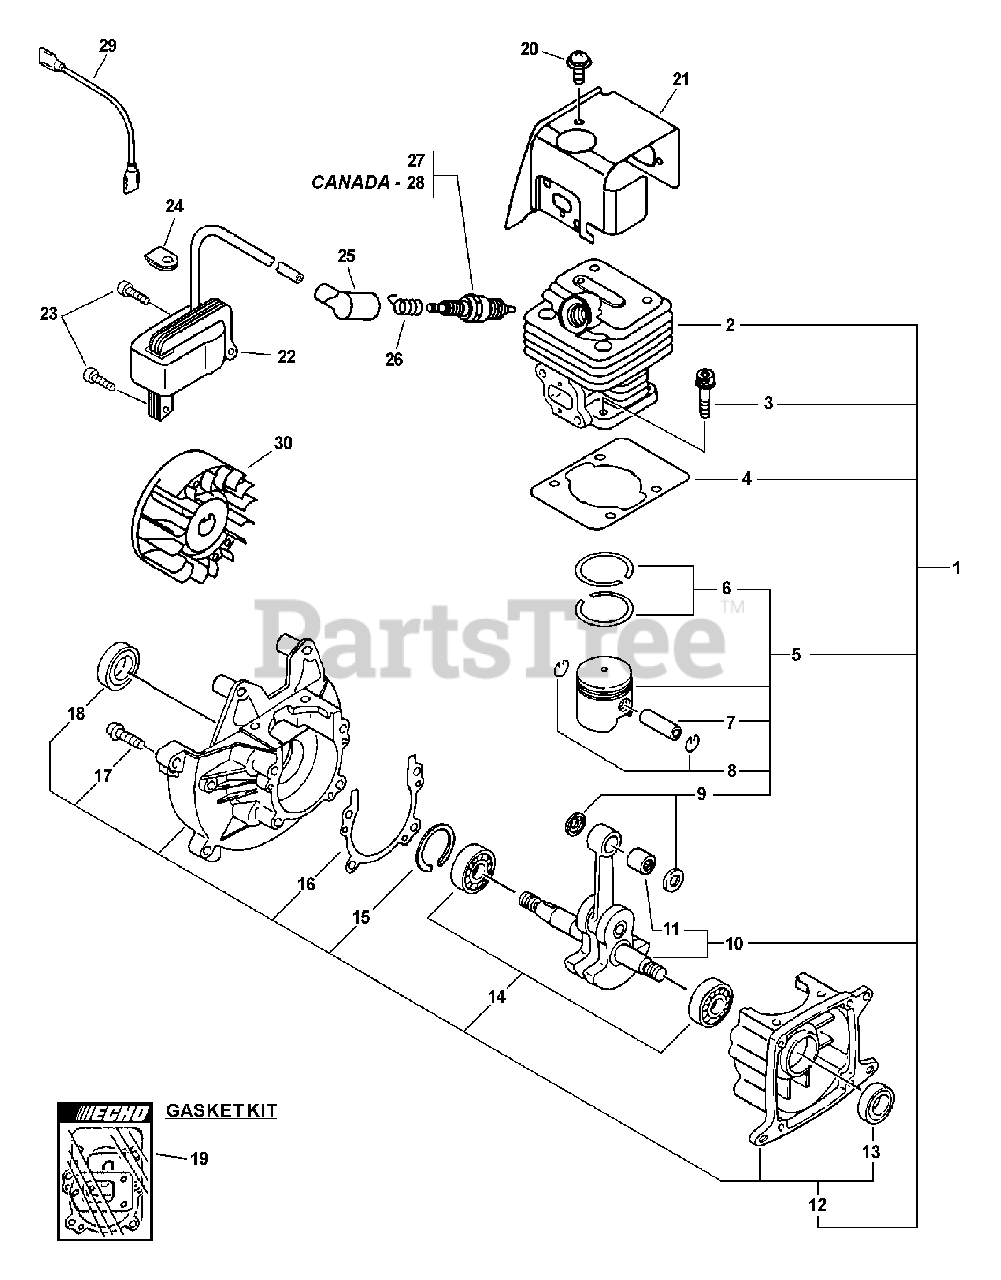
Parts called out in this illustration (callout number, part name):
1	SHORT BLOCK -- SB1045
2	CYLINDER
3	SCREW - 5X22
4	GASKET, CYLINDER
5	PISTON KIT
6	RING, PISTON
7	PIN, PISTON
8	RING, RETAINING
9	SPACER, PISTON
10	CRANKSHAFT ASSY
11	BEARING, NEEDLE - 8
12	CRANKCASE KIT
13	SEAL, OIL
14	BEARING, BALL - 6001C3
15	RING, RETAINING - 28
16	GASKET, CRANKCASE
17	SCREW - 5X25
18	SEAL, OIL - 12
19	GASKET KIT
20	SCREW - 5X10
21	SHIELD, CYLINDER
22	COIL, IGNITION
23	SCREW - 5X16
25	CAP, SPARK PLUG
26	TERMINAL, SPARK PLUG CAP
27	SPARK PLUG -- BPM-7Y
28	SPARK PLUG -- BPMR-7A
29	LEAD - IGNITION
30	FLYWHEEL
